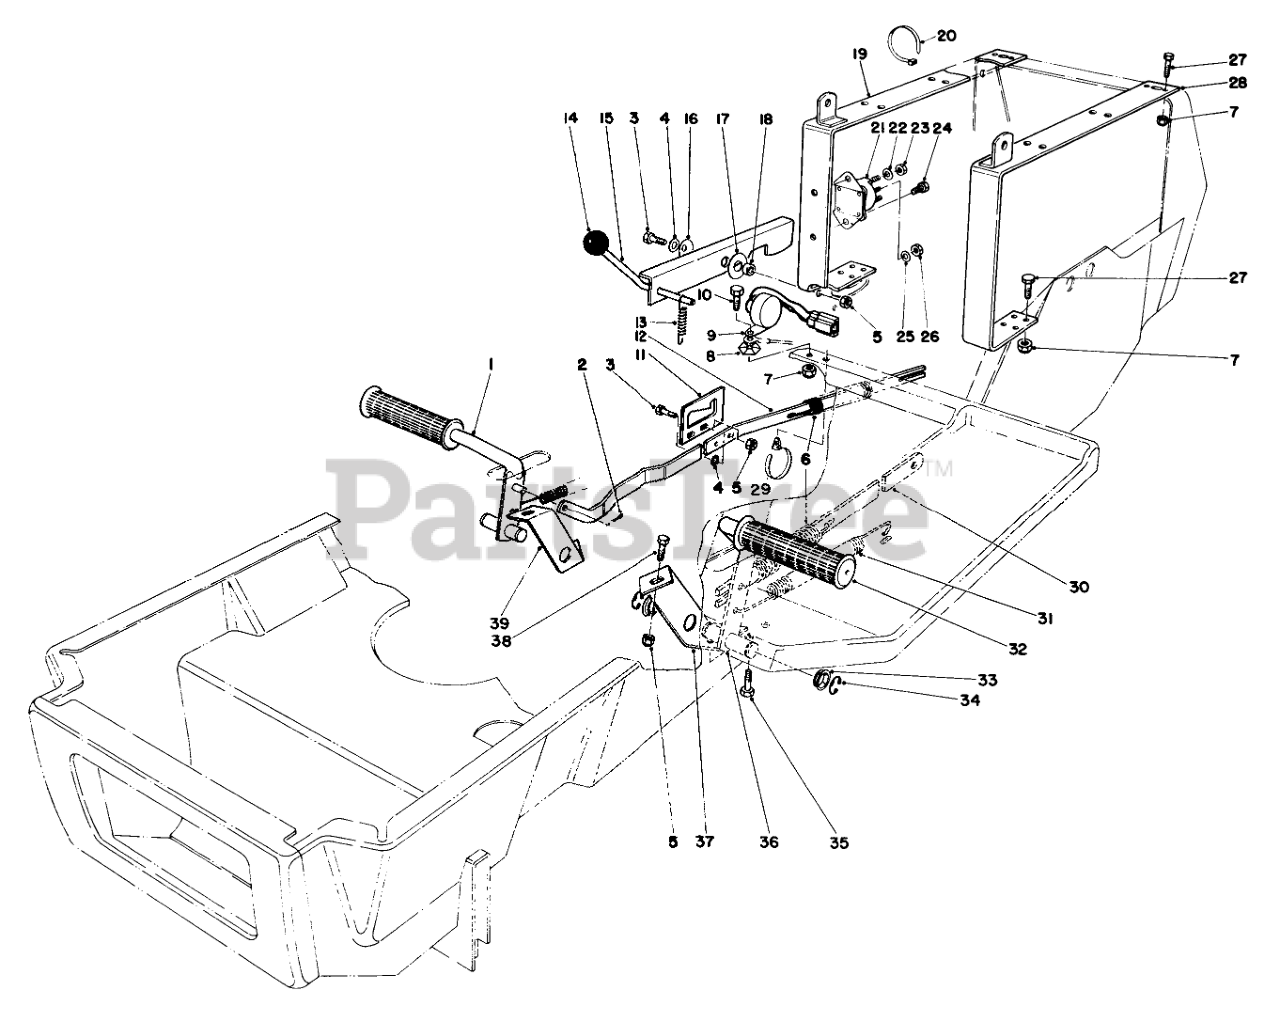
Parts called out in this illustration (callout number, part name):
1	BRAKE PEDAL WA BO
2	PIN-COTTER
3	SCREW-HH
4	WASHER-PLAIN
5	NUT-LOCK, CONE
6	EXT SPRING O
8	Washer
9	Module Interlock
10	Bolt
11	LATCH PLT-BRAKE ROD
12	LINK BRAKE ROD WAB
13	CONT ROD SPRING 0
14	Knob
15	PARKING BRAKE WA B
16	Belleville Washer
17	WASHER-PLASTIC
18	SPACER
19	RR BODY STRAP WA B
20	TIE-CABLE
21	Solenoid
22	Lockwasher
23	NUT-JAM, BRASS
24	SCREW-HWH
25	NUT-HEX
26	WASHER-LOCK
27	SCREW-HH
28	LH RR BODY STRAP WA B
29	10 Pushmount Tie
30	CLUTCH ROD LINK B
31	SPRING-EXTENSION
32	FOOT PAD
33	Nyliner
34	E-RING
35	SCREW-HWHTF
36	CLUTCH PEDAL WA BO
37	LH PEDAL SUPT B
38	SCREW-HH
39	RH PEDAL SUPT B
